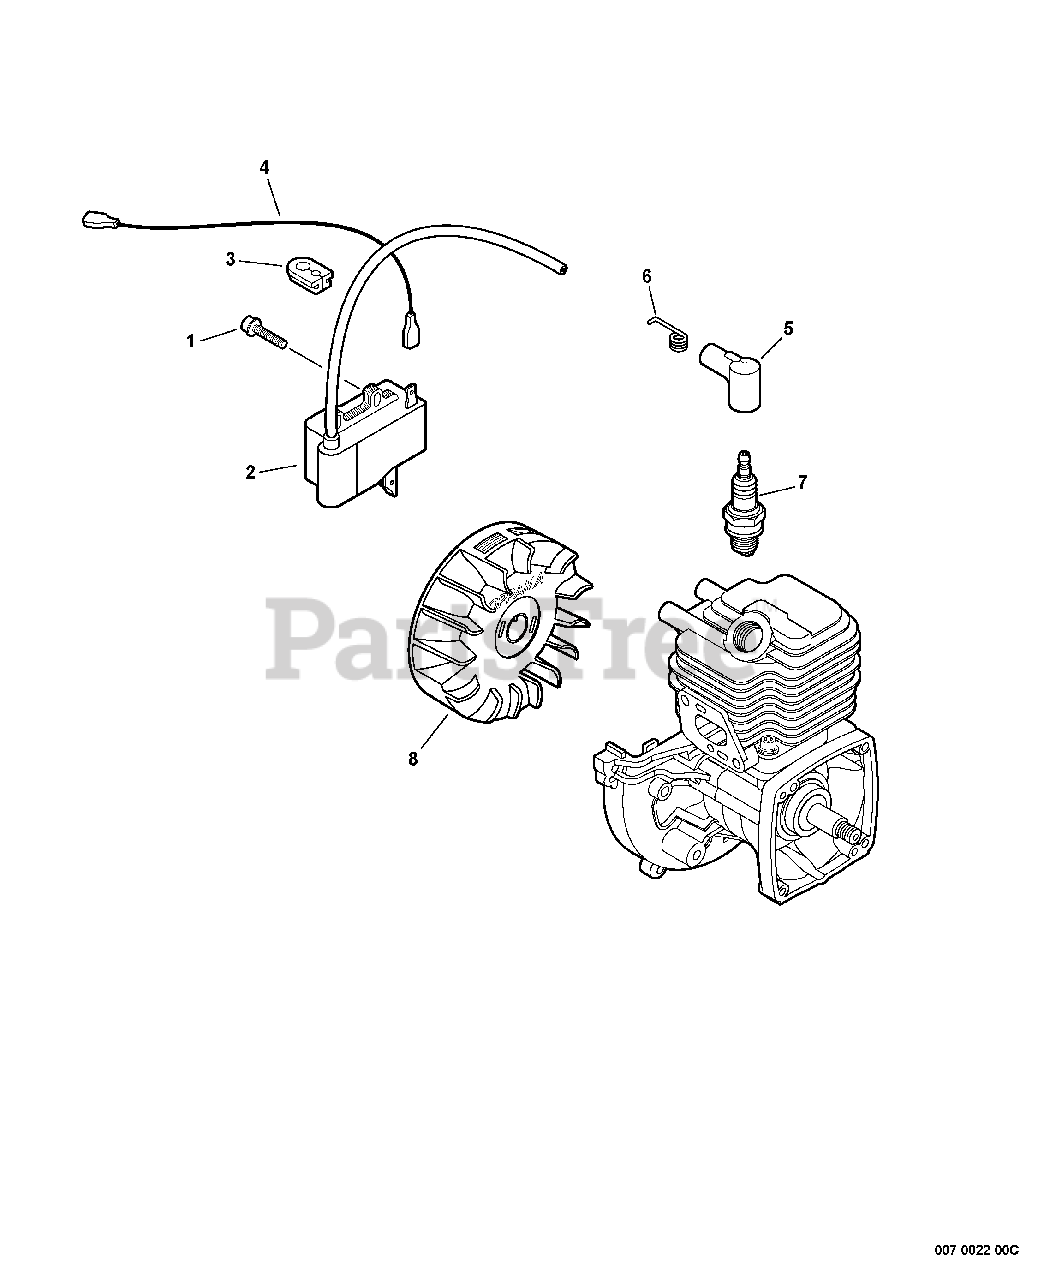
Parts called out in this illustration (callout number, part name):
1	SCREW 4×22
2	COIL, IGNITION
4	LEAD
5	CAP, SPARK PLUG
6	TERMINAL, SPARK PLUG
7	SPARK PLUG - BPM7A
8	FLYWHEEL
